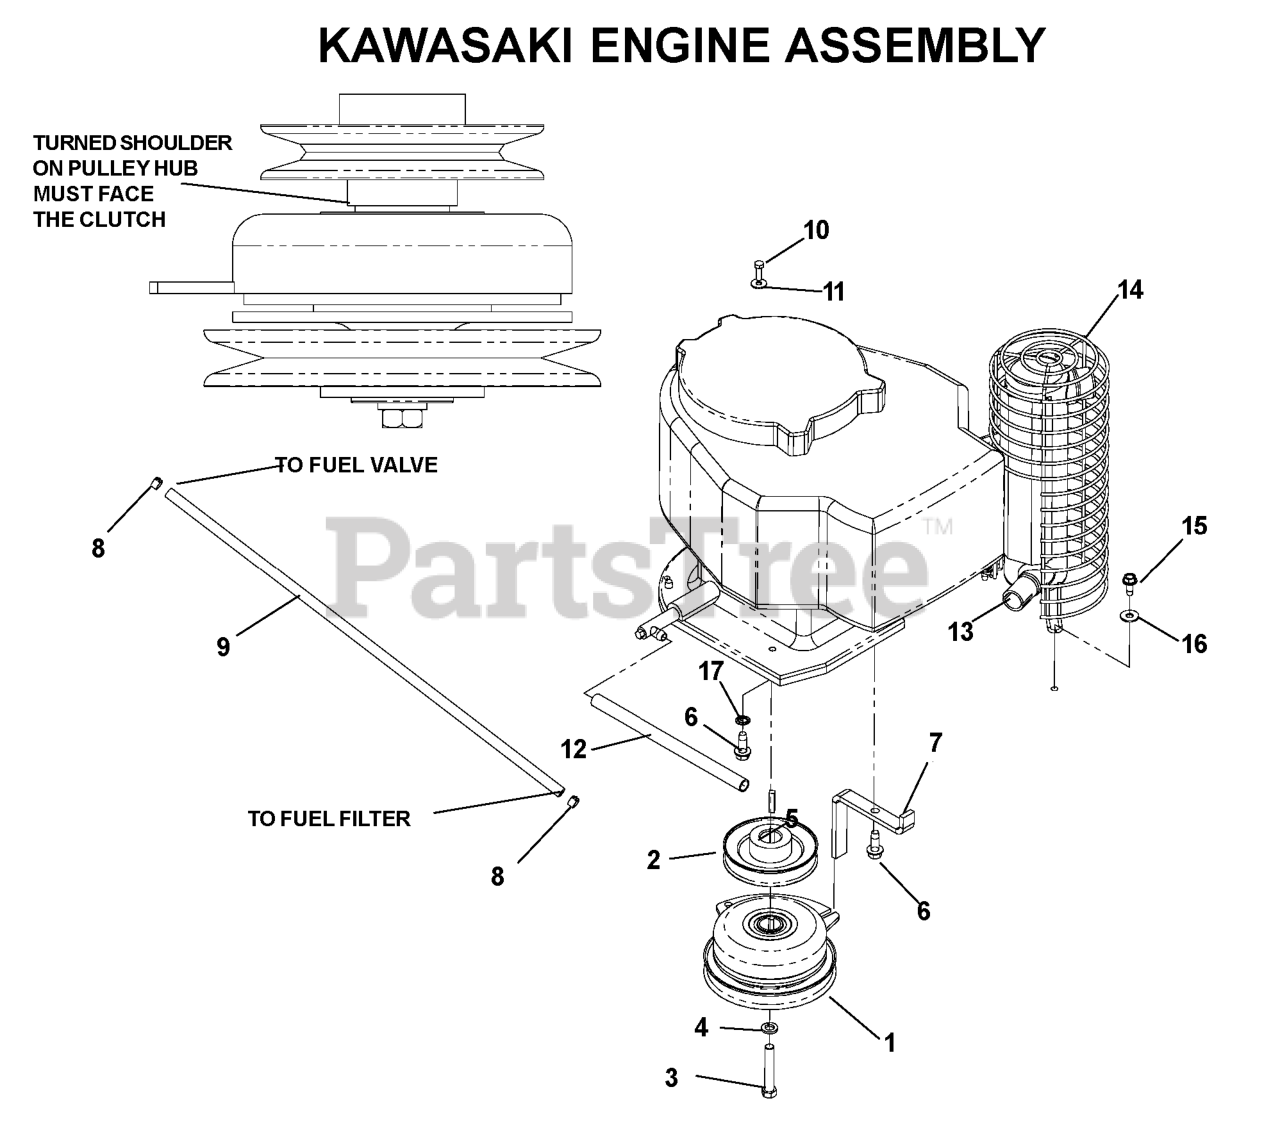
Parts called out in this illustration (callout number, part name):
3	BOLT 7/16F X 2 1/2
4	WASHER 7/16 LOCK
5	KEY 1/4 SQ X 1 1/8
6	BOLT 3/8-16 X 1.0
7	CLUTCH TIE DOWN
8	HOSE CLAMP
9	FUEL LINE 24"
10	HEX HEAD SCREW M6 X 1 X 20
11	WASHER 1/4 FLAT
12	OIL DRAIN HOSE
13	MUFFLER KAW
14	MUFFLER GUARD
15	BOLT 5/16-18 X 3/4
16	WASHER 5/16 FLAT
17	WASHER
539104415	KAW PIGTAIL
539105637	CLUTCH HARNESS
539108120	JAM NUT 1/4C (2 2 PW01)
